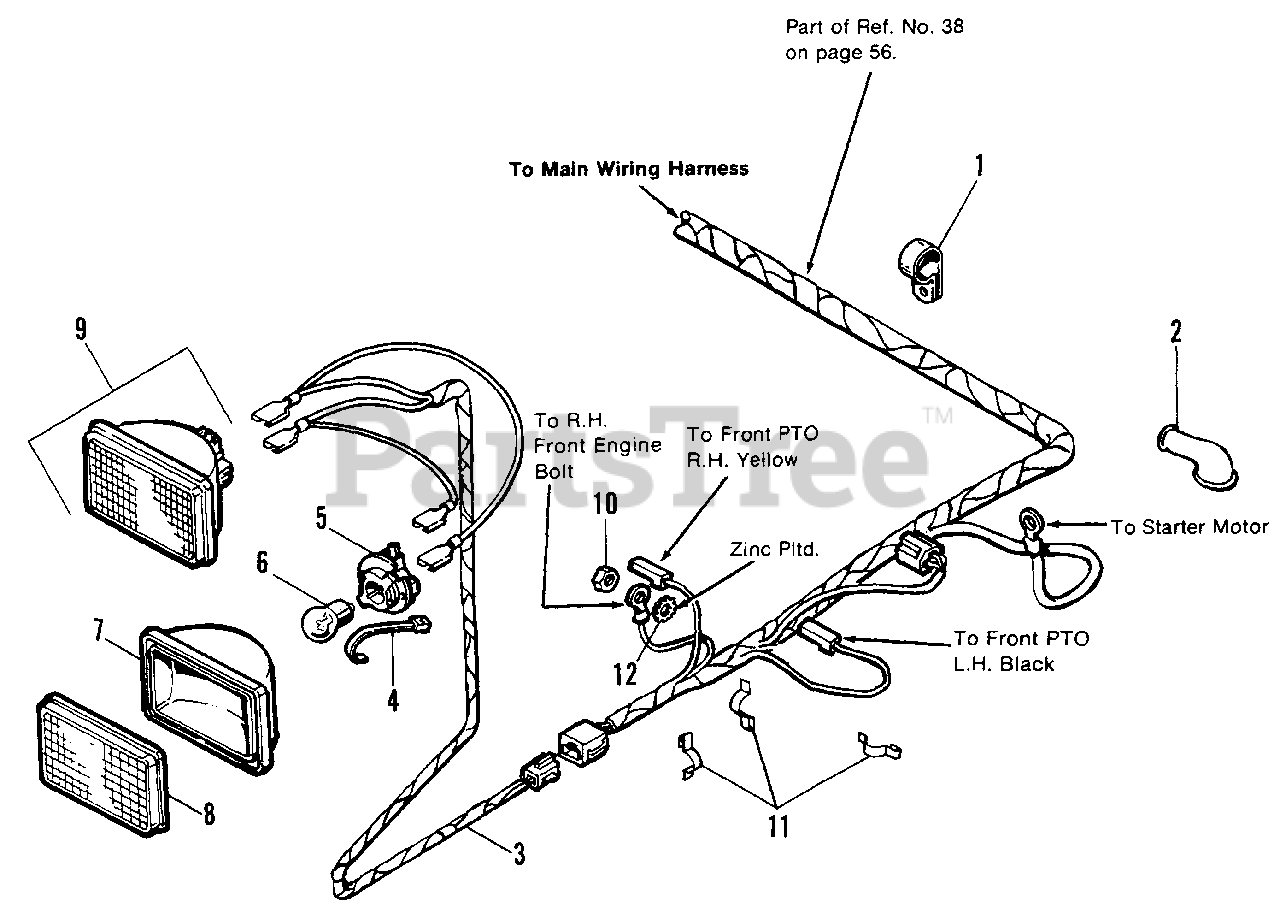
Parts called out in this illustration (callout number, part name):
2	COVER, Terminal
3	HARNESS, Headlight
5	SOCKET, Bulb
6	BULB, 12.8V
8	LENS, Clear
9	HEADLIGHT ASSY. (Incl. Ref. No. 5, 6, 7 & 8)
10	NUT, Jam, Center Lock, 3/8-16
11	CLAMP
12	LOCKWASHER, External Tooth
